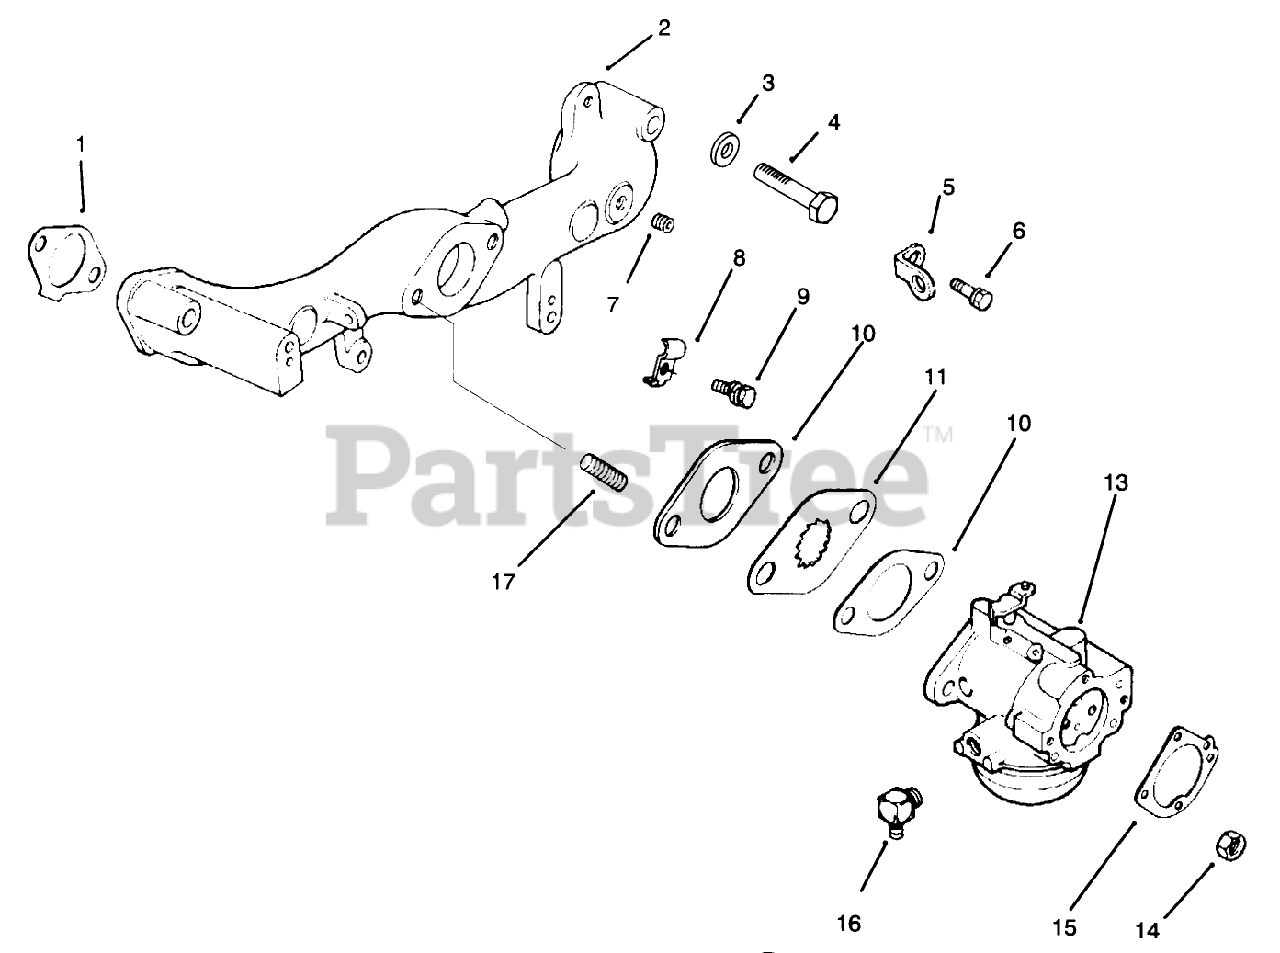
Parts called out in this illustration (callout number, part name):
1	Gasket-Intake Manifold
2	Kit-Manifold (Incl. Ref. #3, 4, 7, & 17)
3	Washer
4	Screw
5	Strap Lifting
6	Screw
7	Plug
8	Clamp-Cable
9	Screw
10	Gasket
11	Baffle
13	Carburetor Kit w/Gaskets
14	Nut
15	Gasket-Elbow
16	Connector-Hose
17	Stud
